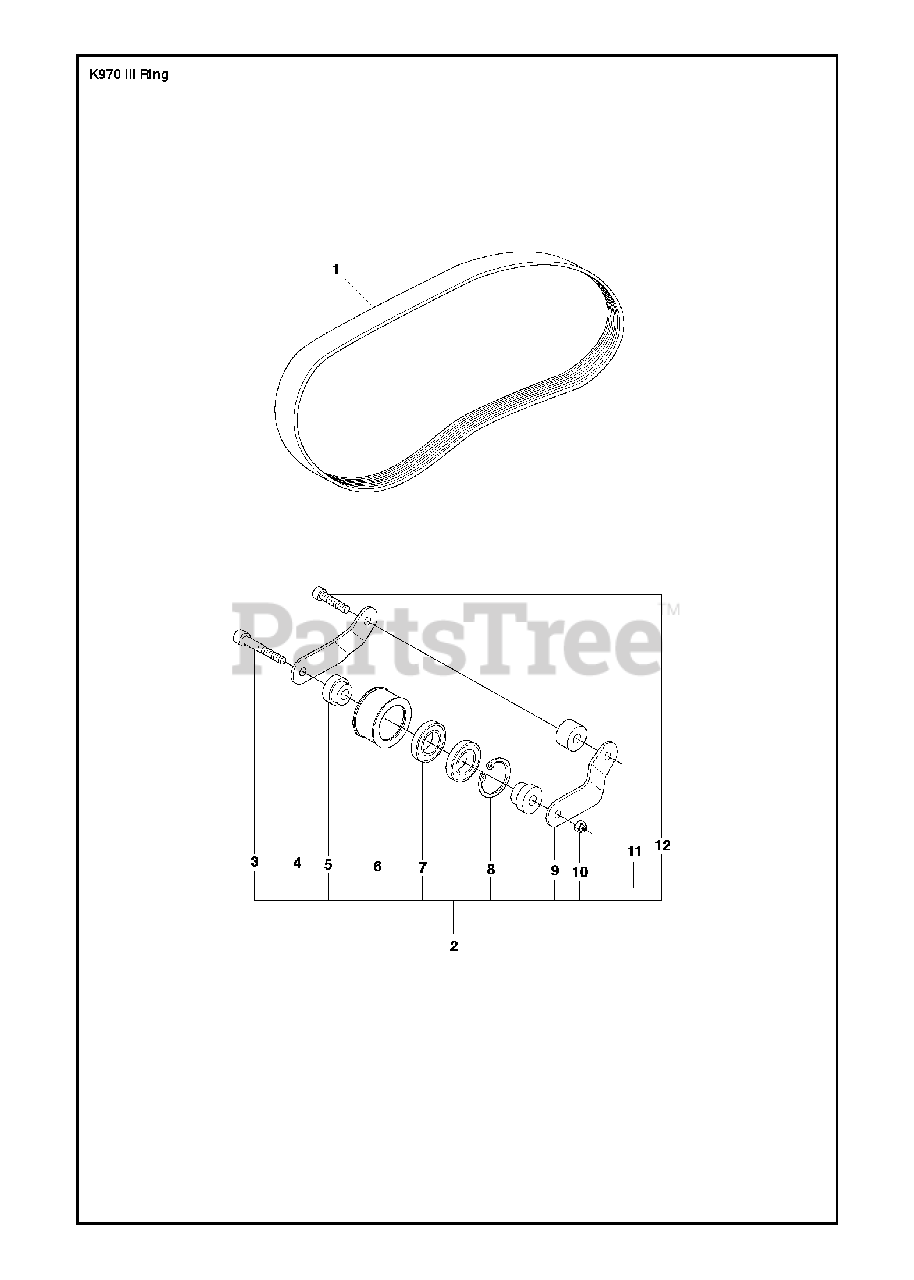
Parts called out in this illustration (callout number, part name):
2	BELT TENSIONER ASSYIncl. 3 - 12
3	SCREW ITXSCM
7	BALL BEARING
10	NUT
12	SCREW ITXSCM
